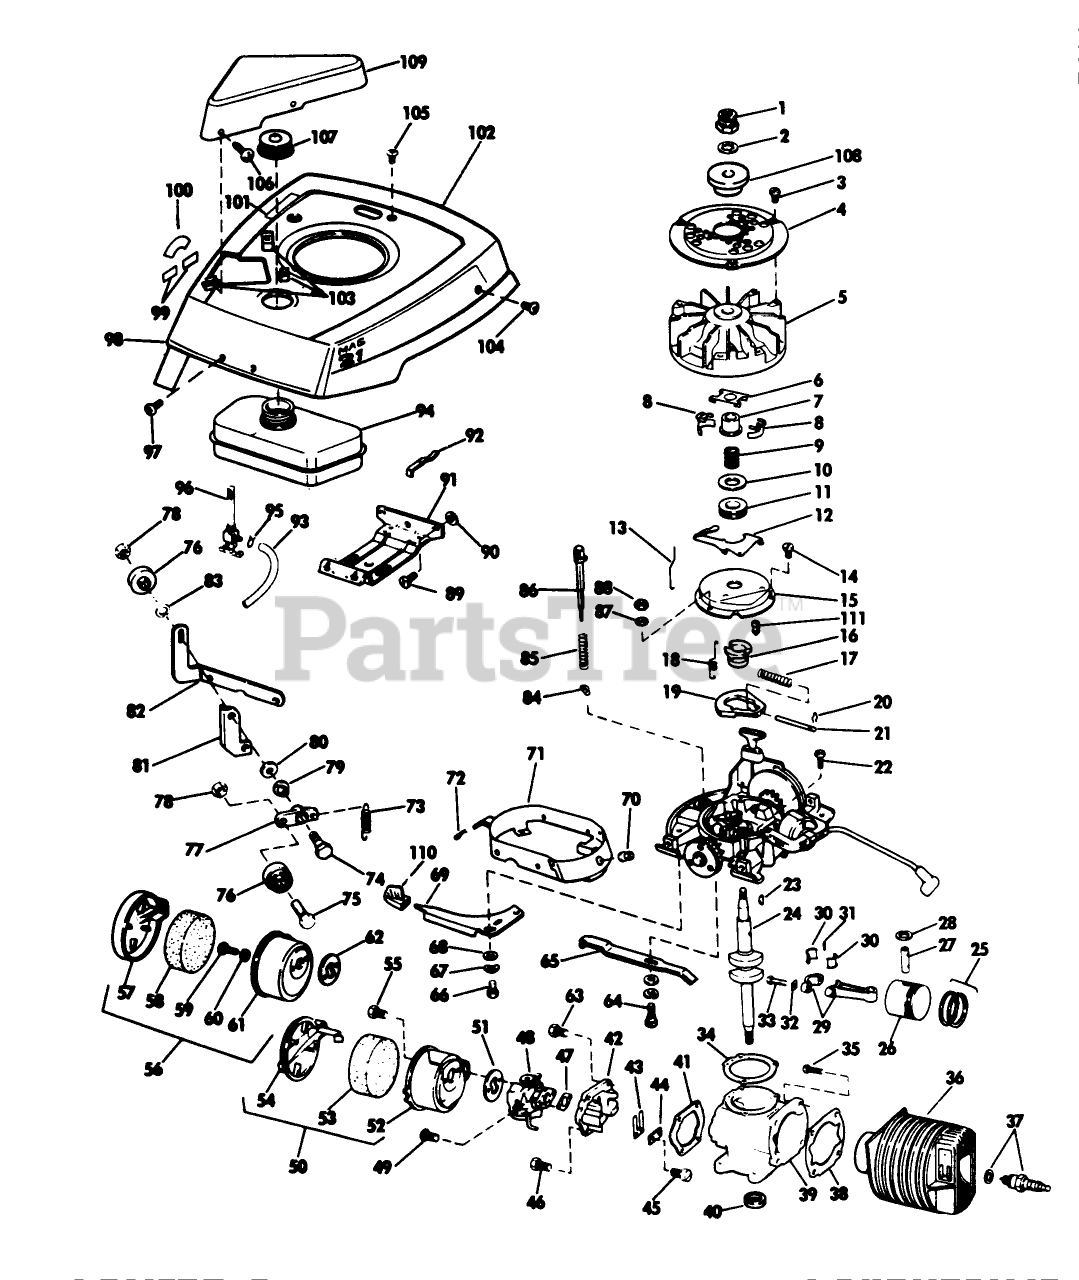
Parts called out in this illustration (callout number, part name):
7	COLLAR S
9	SPRING S
11	THRUST COLLAR S
12	LEVER-GOVERNOR S
14	SCREW S
15	DUST COVER S
16	SPARK ADV. S
17	SPARK ADV. SPRING S
19	FLYWEIGHT S
20	SPARK ADJ. SPRING
21	PIN,SPARK ADV. S
28	RING-RETAINING
30	LINER ASM
34	GASKET S
38	GASKET S
44	PLATE-BACKUP, REED
46	SCREW S
47	GASKET S
51	GASKET S
53	AIR FIL.ELEM S
55	SCREW S
57	CHAMBER AY S
58	AIR FIL.ELEM S
59	SCREW S
61	FILTER CHAMBER S
62	GASKET S
63	SCREW S
70	NUT-CLIP
76	IDLER PULLEY
85	SPRING S
89	SCREW S
93	Gas Line
95	CLAMP - HOSE S
96	VALVE&SCREEN SM
104	SCREW S
